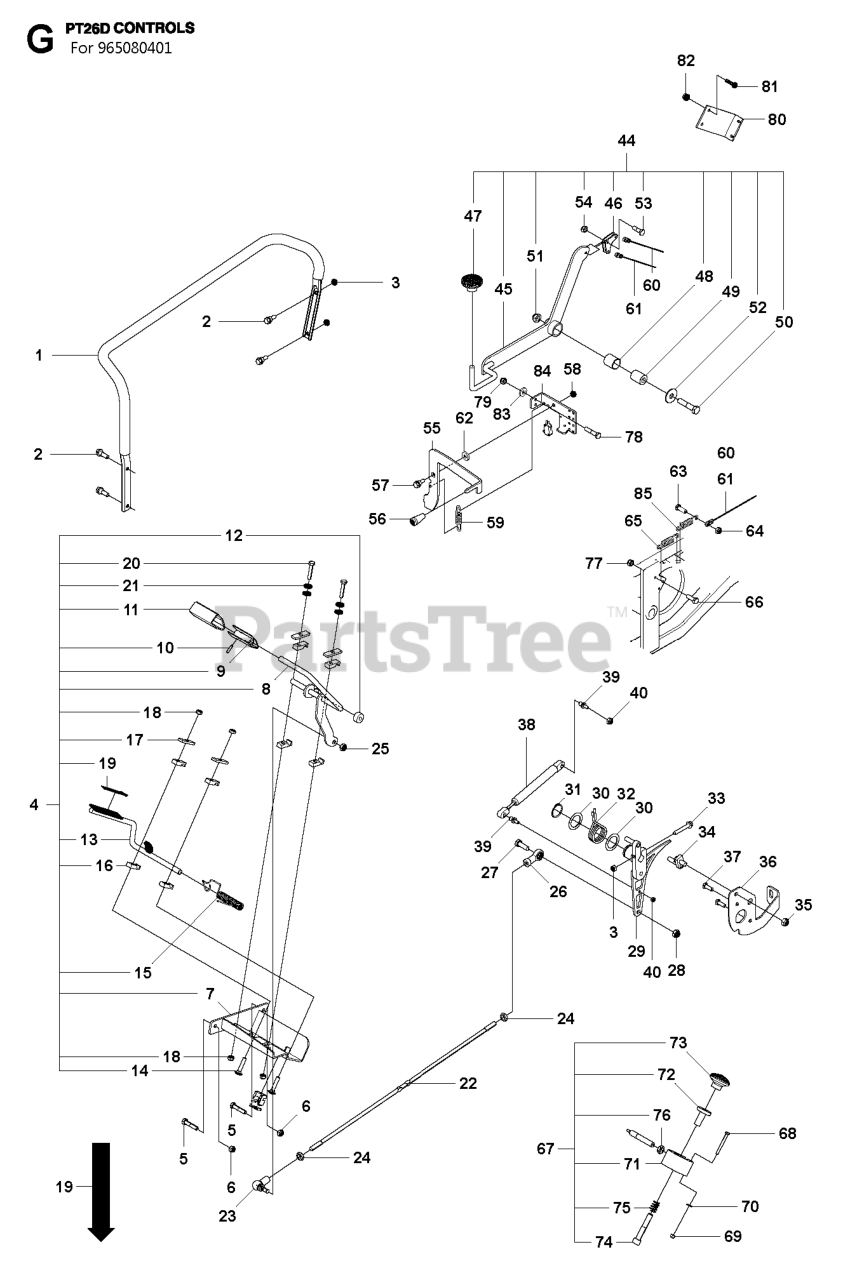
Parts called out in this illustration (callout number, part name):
1	HANDLE ASSY
3	LOCKNUT M8
6	LOCKNUT M8
11	PEDAL RUBBER
14	Screw Mvbf 8 X 40
18	NUT
21	WASHER - 15X7.3X1.6
25	NUT
28	NUT
30	WASHER SPACER 32X45X1,0
33	SCREW
35	NUT
39	CONNECTOR
40	LOCKNUT M6
47	KNOB
48	BUSHING
53	SCREW M6S 5X20
54	LOCKNUT M5
58	LOCKNUT M8
63	SCREW
64	LOCKNUT M8
66	SCREW M6S 5X20
68	SCREW M6X55
69	LOCKNUT M6
70	WASHER
73	KNOB
77	LOCKNUT M5
79	LOCKNUT M6
81	Screw
82	LOCKNUT M6
83	WASHER
